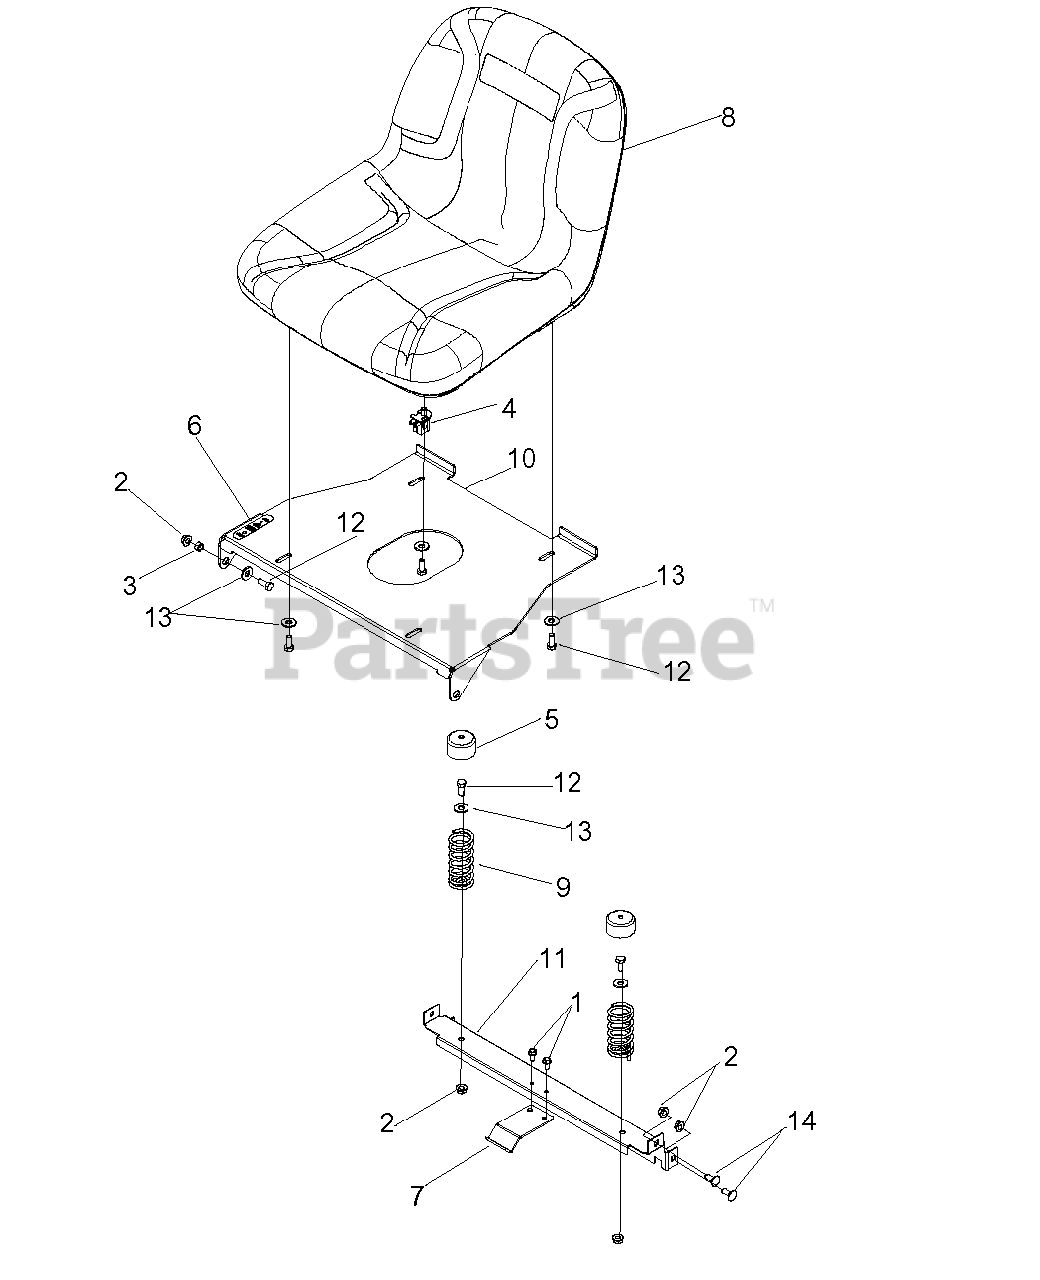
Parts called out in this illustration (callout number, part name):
1	1/4-20 X 1/2 HWH FORM SCR H
2	5/16-18 FLANGED L-NUT
4	SEAT SWITCH
5	SPRING CAP
6	DECAL, PARK BRAKE
7	HOLD DOWN
8	TEXAS MID BACK SEAT
9	SEAT SPRING
10	SEAT PLATE (BLUE)
11	CROSS MEMBER (BLUE)
12	HCS 5/16C X 3/4
13	FLAT WASHER 5/16 SAE
14	BOLT 5/16C X 3/4" CARRIAGE
